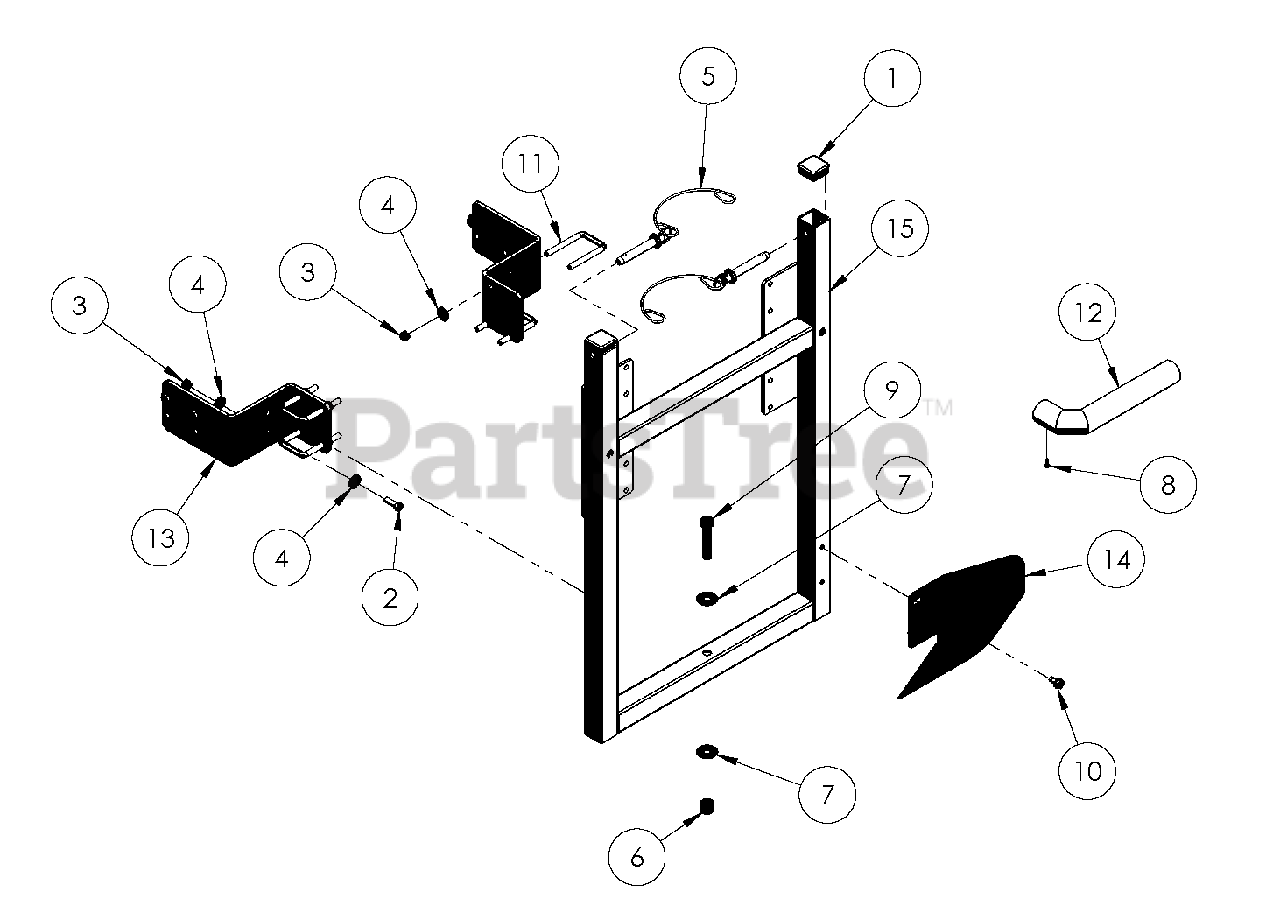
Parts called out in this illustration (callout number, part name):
1	Plug, Sq. Hole
2	Cap Screw 5/16- 18 X 1
3	5/16- 18 Nylon Insert Nut
4	5/16" Flat Washer
5	1/2 Detent Pin 2.5" Long
6	1/2 - 13 X Nylon Insert Nut
7	1/2" Flat Washer
8	#10 X 1/2" Lg Sheet Metal Screw
9	CS 1/2-13 X 2.5 G5
10	5/16 X 5/8" Self Tap Screw
11	5/16- 18 X 2" W X 3" Lg Sq U-Bolt
12	Exhaust Extension Assembly
13	Leg Set Mounting Bracket - Pro Series
14	Heat Shield
15	3 Bag Catcher Mount
